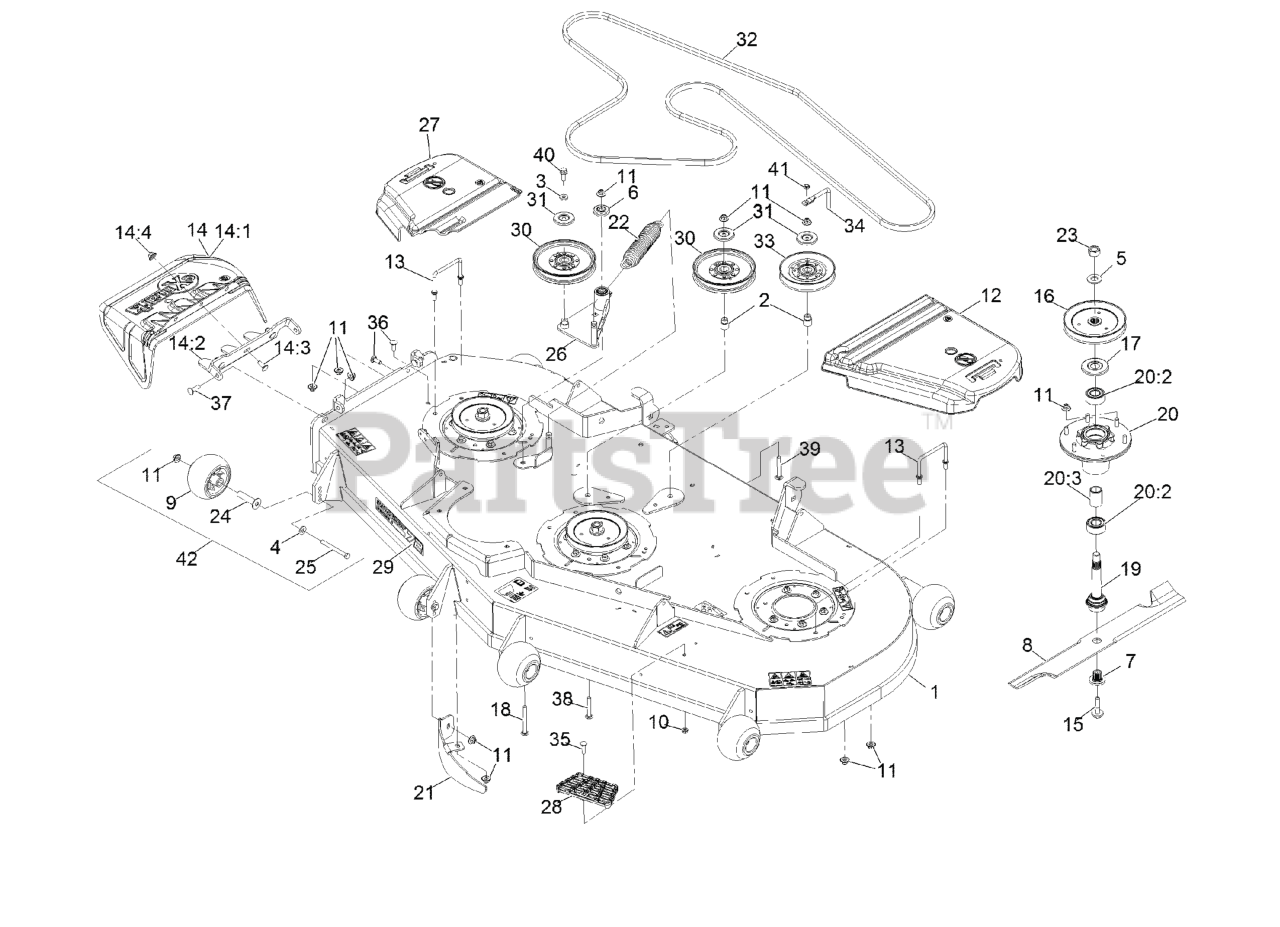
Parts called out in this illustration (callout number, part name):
1	DECK-724
2	BUSHING-IDLER
4	WASHER-BELLEVILLE
6	GUARD-TOP
7	BUSHING,SPLINED
9	ROLLER-SCALP, ANTI
10	NUT-HF, NI
11	Nut-Nyloc 3/8-16 Flg
12	COVER-BELT, LH
13	WIREFORM-COVER
14	ASM,DISCHARGE CHUTE
14:1	CHUTE,DISCHARGE
14:2	BRACKET,DISCHARGE CHUTE
14:3	SCREW-CARR
14:4	Nut-Nyloc 3/8-16 Flg
15	SCREW,SEMS 1/2-20 X 2.19
16	SHEAVE,BLADE DRIVE 6.50
17	GUARD-BEARING, TOP
18	BOLT-SHOULDER, CARRIAGE 3/8-16 X 3 1/2
19	ASM-SPINDLE AND SEAL
20	ASM-CUTTER HSG
20:2	BEARING-3205 TRASHGUARD
20:3	SPACER-BEARING
21	BAFFLE-DOGLEG, LZ72
22	SPRING-EXTENSION
23	NUT-HEX
24	AXLE, ROLLER
25	SCREW-HH 3/8-16 X 3 3/4 GR 8
26	IDLER ARM ASM
27	SHIELD-BELT
28	STEP-DECK
29	DECAL, 724
30	IDLER-PULLEY
31	SHIELD-DUST
33	IDLER V
34	GUIDE-BELT
35	Bolt-Carriage 5/16-18 X 1 1/4
36	SCREW-CARR
37	Bolt-Carriage 3/8-16 X 1 1/4
38	SCREW-CARR
39	SCREW-CARR
40	SCREW-HHF
42	KIT, ANTI-SCALP ROLLER
